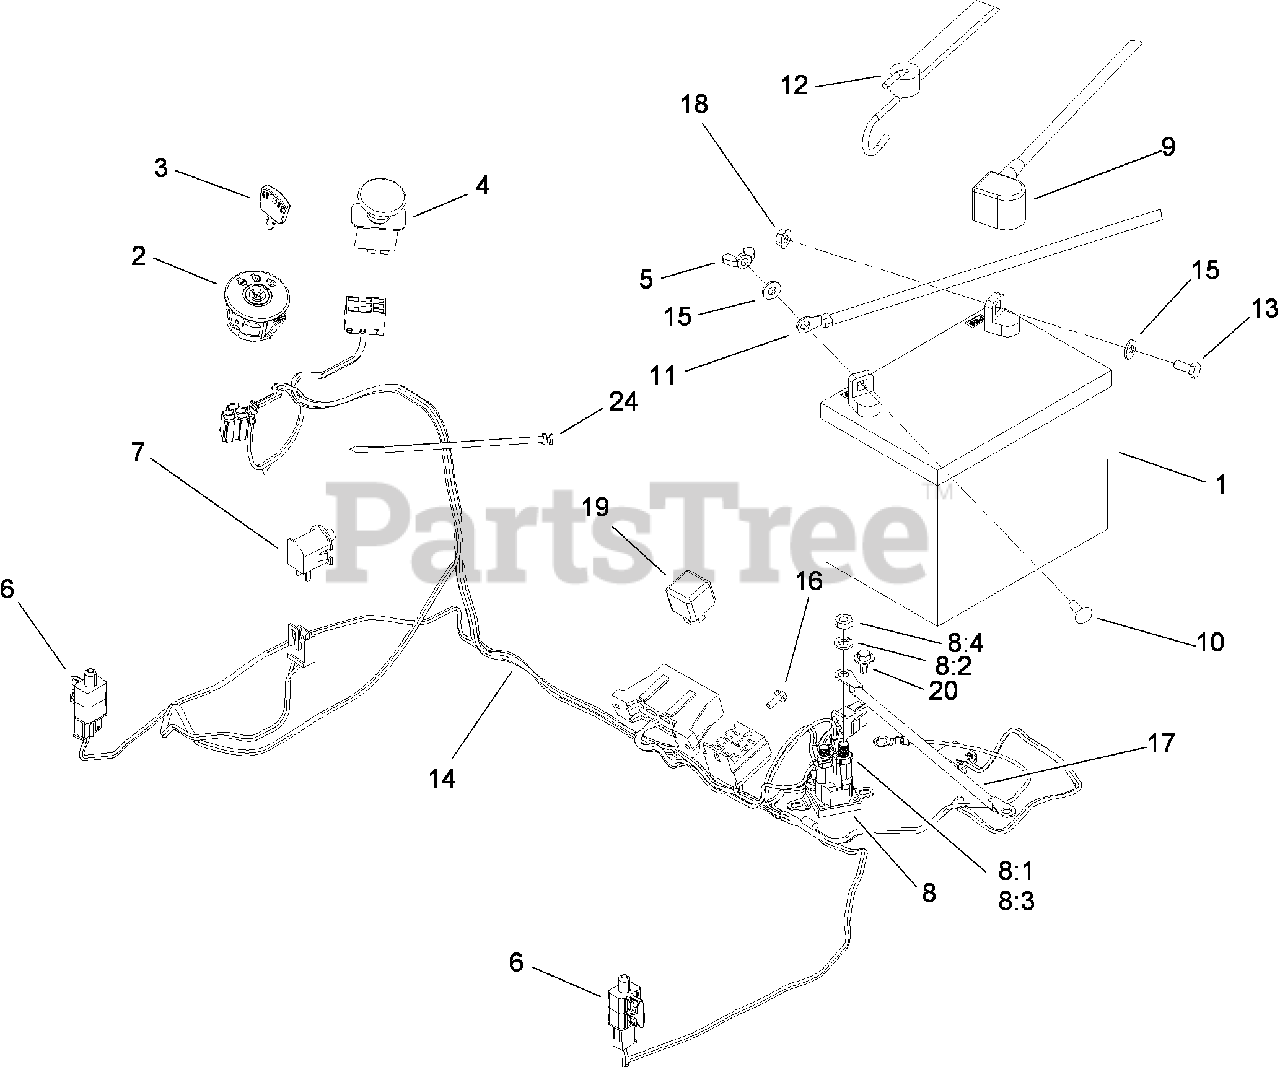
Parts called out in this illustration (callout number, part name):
1	BATTERY
2	SWITCH-IGNITION
4	SWITCH-PTO
6	SWITCH-SINGLE POLE NO
7	SWITCH-BAIL
8	SWITCH-SOLENOID
8:1	WASHER-LOCK
8:2	WASHER-LOCK
8:4	NUT-JAM
9	CABLE-BATTERY, RED
10	SCREW-CARR
11	CABLE-BATTERY, BLACK
12	HOLDDOWN-BATTERY
13	SCREW-HH
14	HARNESS-WIRE
15	WASHER-FLAT
16	SCREW-TAPTITE
17	CABLE-BATTERY, RED
20	SCREW-HHF
24	STRAP-TIE
